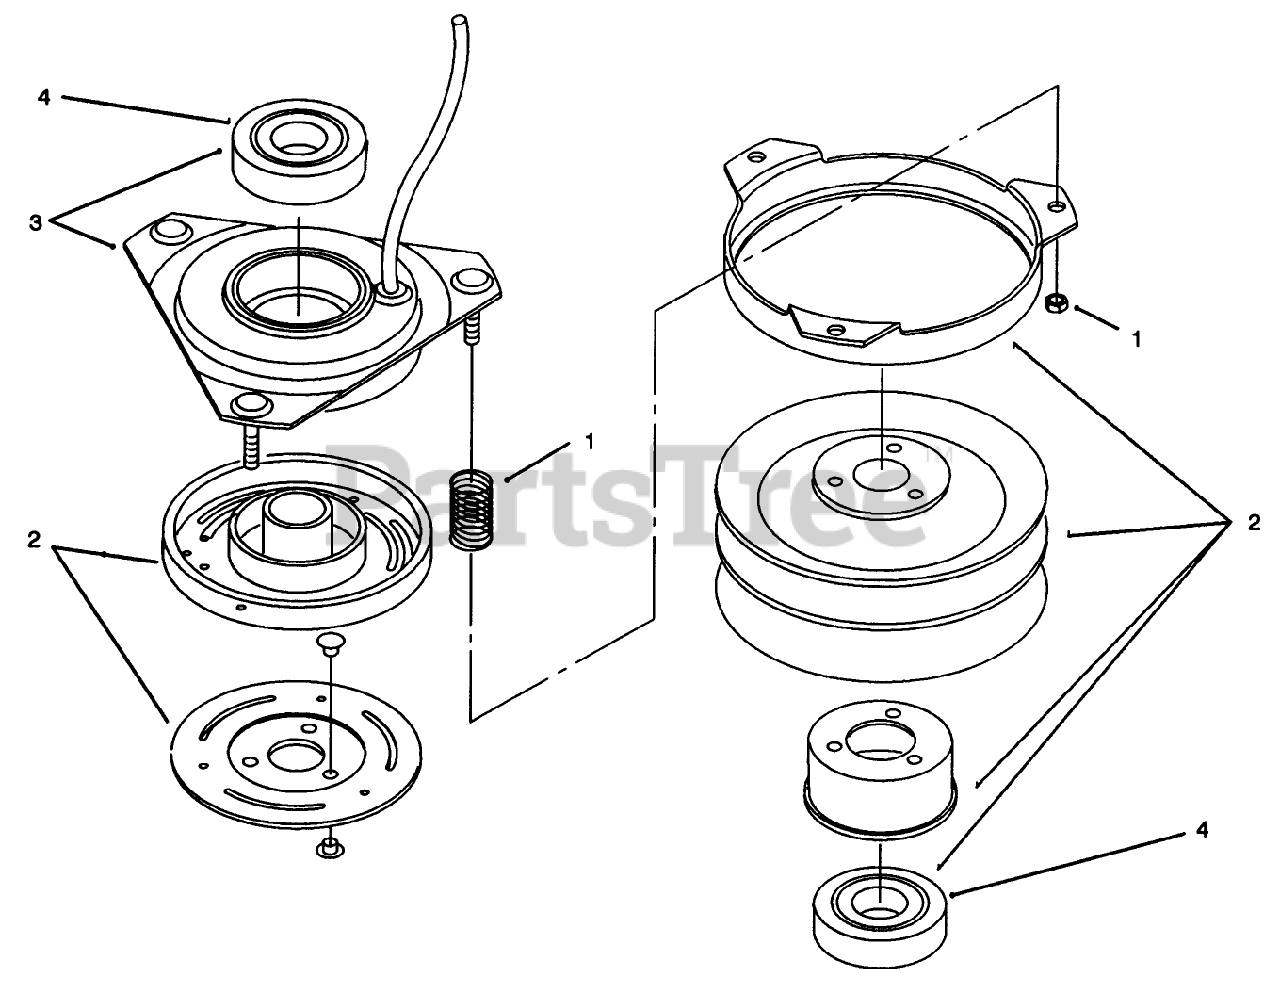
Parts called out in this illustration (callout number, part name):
1	ACCESSORY PKG SRVC PART
2	ASM - ROTOR/ARMATURE
3	FIELD ASSY (SRVC PART)
4	BEARING-ELEC CLUTCH
